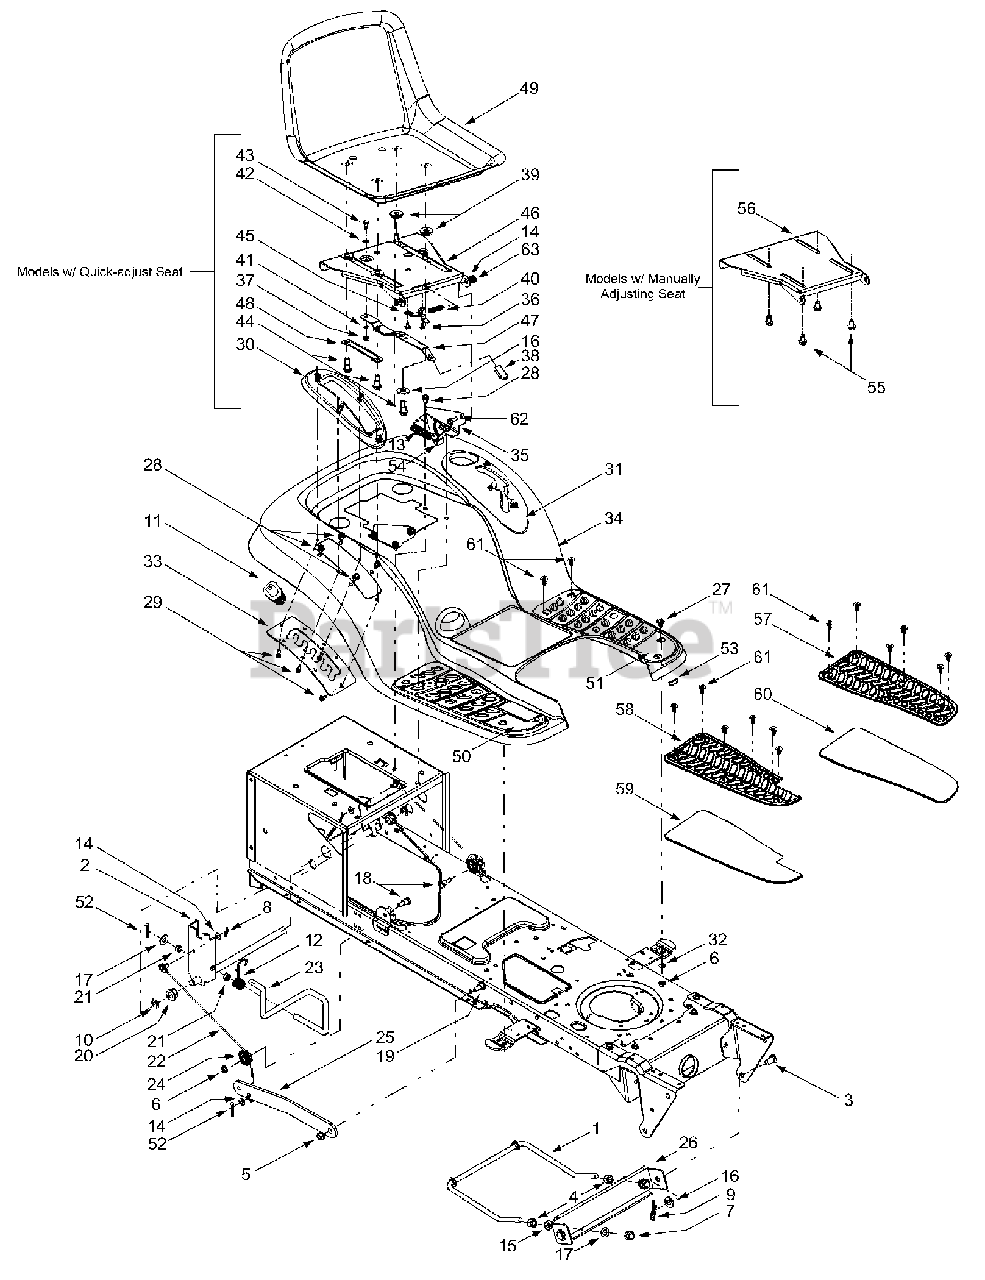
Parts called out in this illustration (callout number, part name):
1	Deck Stabilizer Rod
3	Clevis Pin, .5 x .78
4	Hex Nut, 1/2-13
5	Flange Lock Nut, 3/8-16
6	Flange Lock Nut, 5/16-18
7	Hex Nut, 1/2-13
8	Internal Cotter Pin
9	Internal Cotter Pin
10	E-ring
11	Handle Grip
12	Torsion Spring
13	Extension Spring, .84 x 4.6
14	Flat Washer, 5/16
15	Lock Washer, 1/2
16	Flat Washer, .31 x 1.062 x .134
17	Flat Washer, .51 x 1.12 x .06
18	Hex Cap Screw, 5/16-18 x .62
19	Shoulder Screw, 3/8-16
20	Hex Flange Bearing
21	Snap Flange Bearing
22	Lift Cable, 16.16
23	Lift Handle
24	Roller Pulley
27	Carriage Bolt, 5/16 x .62
28	Self-tapping Screw, 5/16-18 x .625
29	Self-tapping Screw, 1/4-15 x .75
30	Lift Lever Cover
31	Shift Lever Cover w/ Cup Holder
32	Flat Washer, .349 x 1.0 x .063
36	Screw, #10-16 x .375
37	Hex Flange Lock Nut, 1/4-20
38	Seat Adjuster Grip
39	Spacer
40	Compression Spring, .41 x 1.5
41	Spring Washer, .265 x .562 x .025
42	Flat Washer, .344 x .62 x .03
43	Shoulder Screw, .340 x .285,1/4-20
44	Shoulder Screw, .50 x .50, 3/8-16
45	Seat Stop
48	Seat Adjustment Selector
49	High Back Seat, Black
50	RH Foot Pad, Rubber (4-Style Fender)
51	LH Foot Pad, Rubber (4-Style Fender)
52	Cotter Pin
53	Trim Strip
54	Seat Lift Bracket
55	Hex Head Washer Screw, 3/8-16 x .625
58	LH Foot Pad, Rubber (7-Style Fender)
59	RH Foot Pad, Grit (7-Style Fender)
60	LH Foot Pad, Grit (7-Style Fender)
61	Ratchet Clip
62	Shoulder Screw, .437 x .286
63	Speed Nut, .3125
